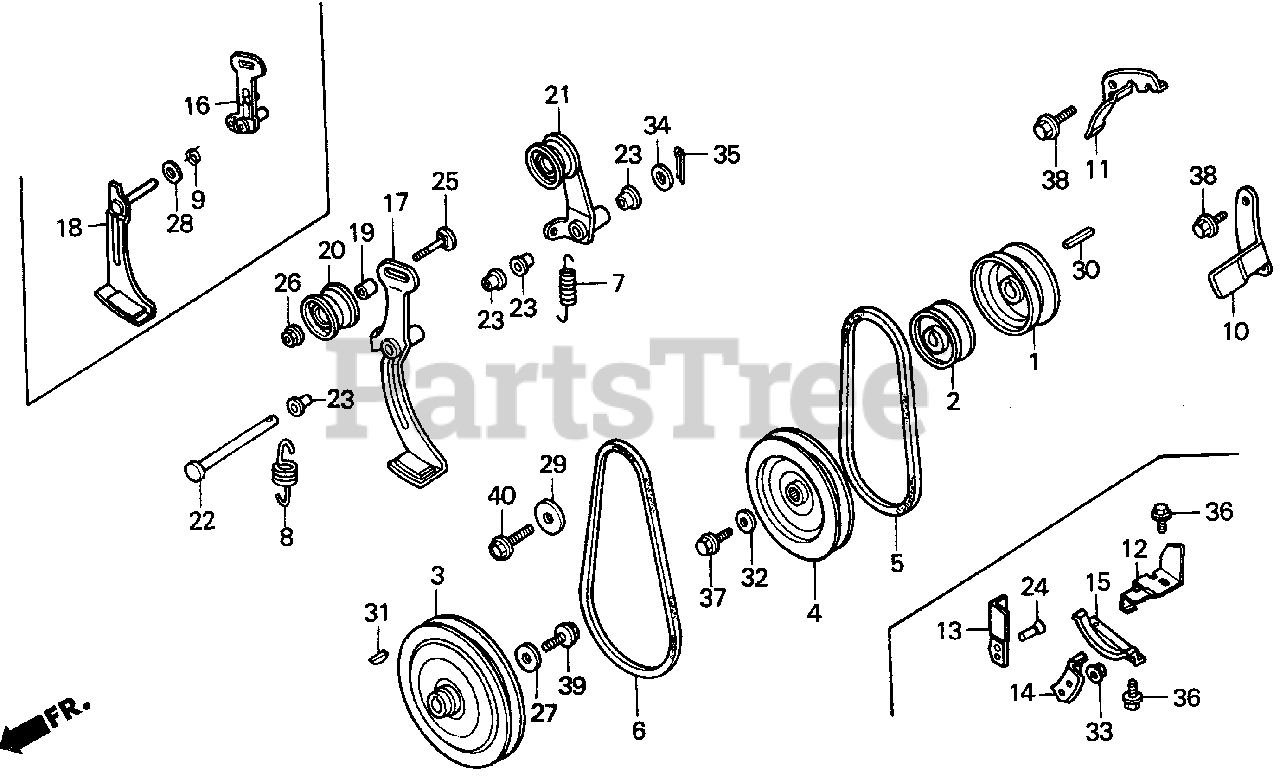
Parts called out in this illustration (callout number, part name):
1	PULLEY, WHEEL DRIVEN
2	PULLEY, AUGER DRIVE (NOT AVAILABLE)
3	PULLEY, AUGER DRIVEN
4	PULLEY, WHEEL DRIVEN
5	V-BELT (SA-32)
6	V-BELT (SB-35)
7	SPRING, TENSIONER RETURN (WHEEL) (NOT AVAILABLE)
8	SPRING, AUGER TENSIONER RETURN
9	SPRING, BRAKE ARM
10	STOPPER, R. BELT
11	STOPPER, L. BELT
12	GUIDE, BELT
13	STOPPER, L. BELT
14	STOPPER, R. BELT
15	STOPPER, BELT (WHEEL)
16	ARM, AUGER TENSIONER
18	ARM, AUGER BRAKE
19	COLLAR, ROLLER
21	ARM, WHEEL TENSIONER
23	BUSH, TENSIONER ARM
24	BOLT, DOOR LOCK STRIKER
25	BOLT, ROLLER
26	NUT, SELF-LOCK (8MM)
27	WASHER, SPECIAL (28X8.5X4.0)
28	WASHER, BRAKE ARM
29	WASHER, LOCK (8MM)
30	KEY (7X7X33)
32	WASHER, CAMSHAFT SIDE
33	NUT, FLANGE (6MM)
34	WASHER, FLAT (12MM)
35	PIN, COTTER (3.0X18)
36	BOLT, FLANGE (6X12)
36	BOLT, FLANGE (6X14)
37	BOLT, FLANGE (6X16)
38	BOLT, FLANGE (8X16)
39	BOLT, FLANGE (8X22)
40	BOLT, FLANGE (8X28)
